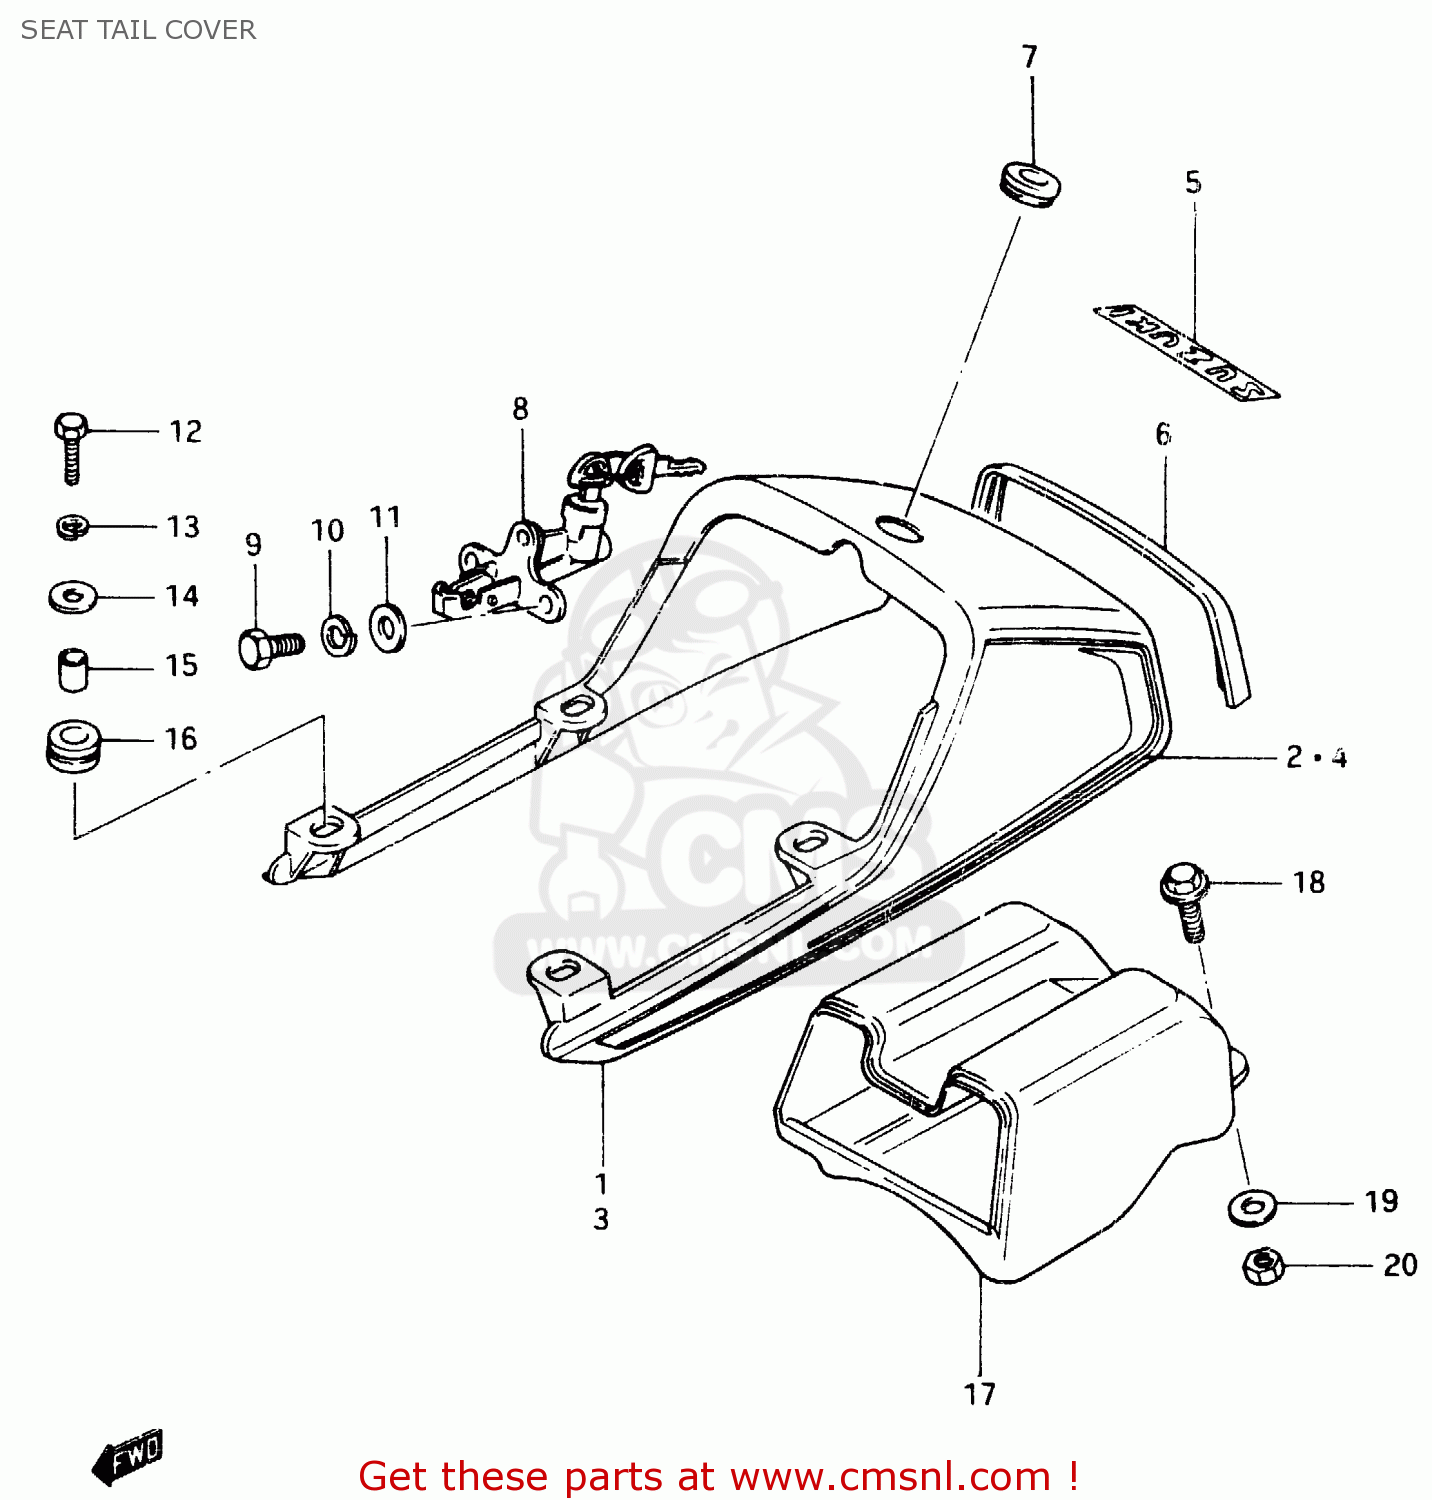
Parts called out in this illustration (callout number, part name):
1	COVER,SEAT TAI
2	TAPE SET, SEAT TAIL COVER
3	COVER, SEAT TAIL (RED)
4	TAPE SET, SEAT TAIL COVER
5	EMBLEM,SEAT TAIL(SILVER)
6	CUSHION
7	GROMMET,SEAT LOCK HOLE
8	LOCK SET,SEAT
9	BOLT
10	LOCK WASHER
11	WASHER
12	BOLT
13	LOCK WASHER
14	WASHER(6,5X22X1.6)
15	SPACER(6.5X10.5X12)
16	CUSHION
17	BOX, SEAT TAIL
18	BOLT
19	WASHER
20	NUT
